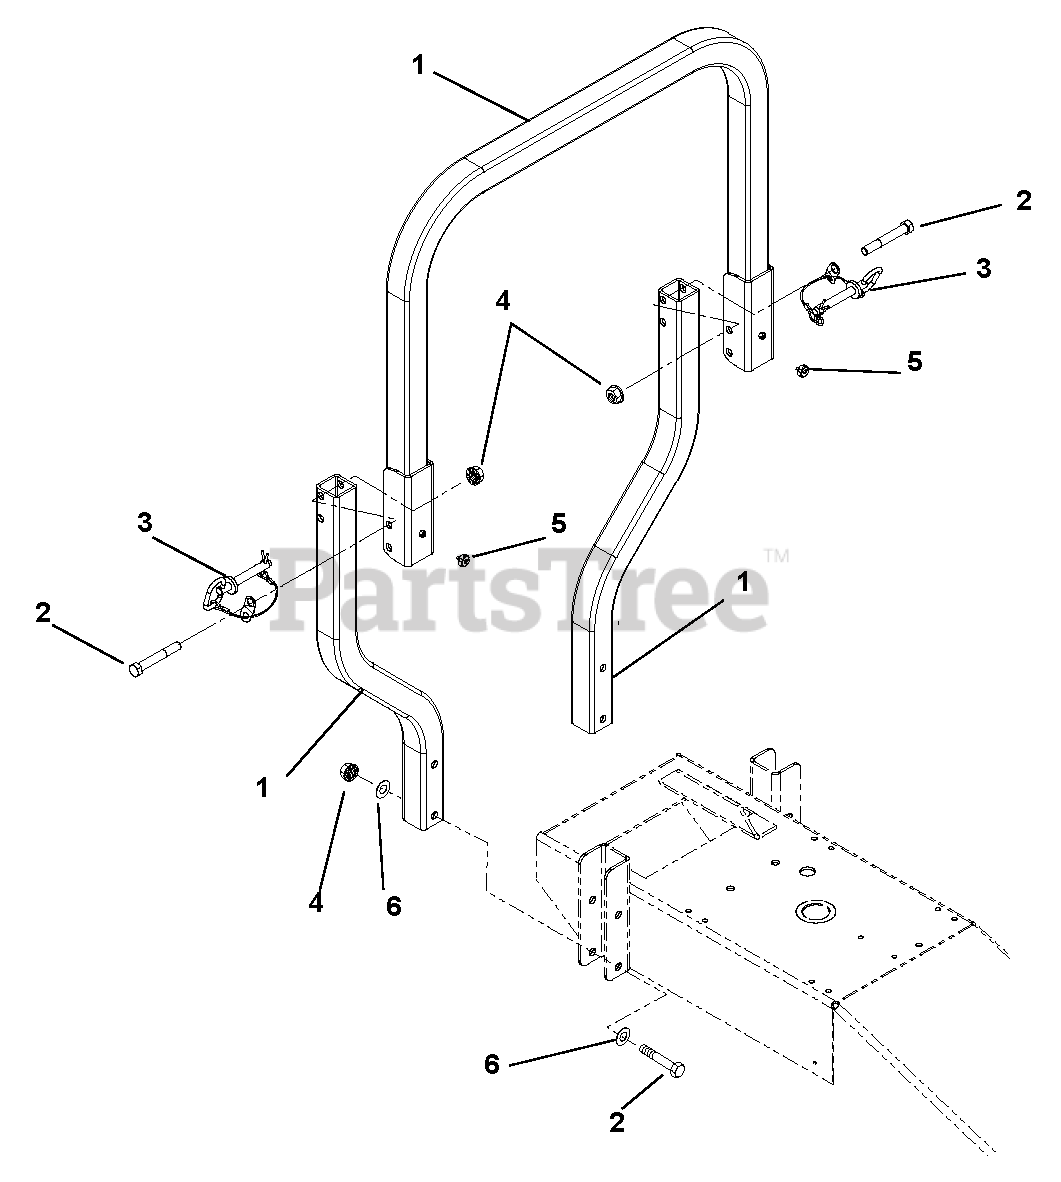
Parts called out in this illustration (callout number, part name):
1	ROPS, PM320 Replacement Kit
2	Bolt, Hex .50-13 x 3.50 Grade 5
3	Assembly, ROPS PIN/LANYARD
4	Nut, Locking-Top-Flange .50-13
5	Knob, Round .312-18 x .750
5	Clip, ROPS Hoop
6	Washer, Flat Steel .563 x 1.38 x .109 YWZC
